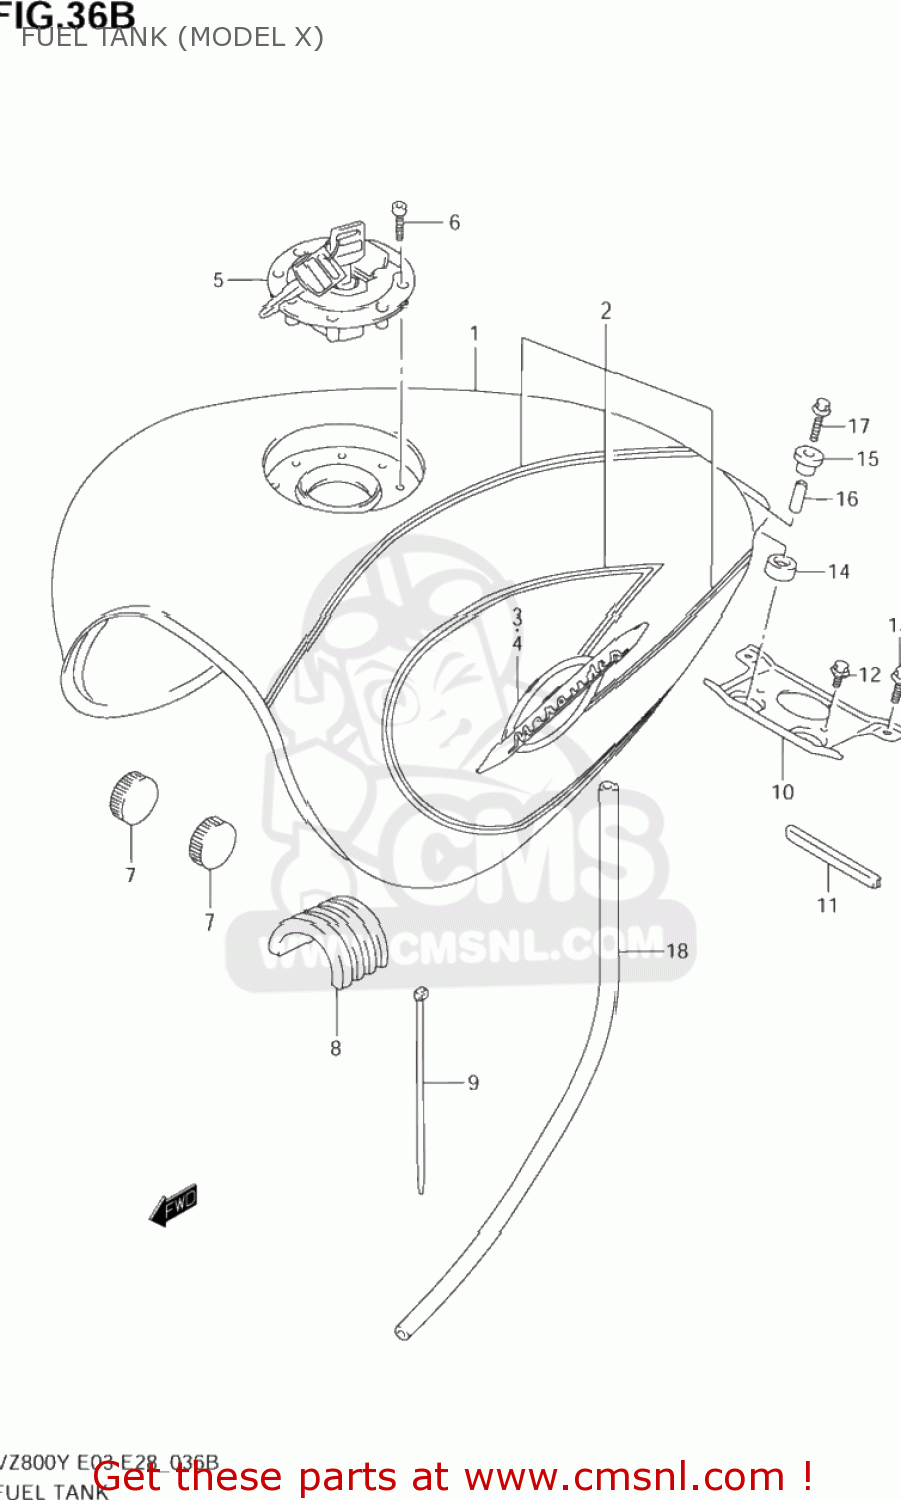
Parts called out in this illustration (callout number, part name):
1	TANK ASSEMBLY,FUEL
2	TAPE SET,FUEL TANK
3	EMBLEM,FUEL TANK,R
4	EMBLEM,FUEL TANK,L
5	CAP SET,FUEL TANK
6	BOLT(5X20)
7	CUSHION
8	CUSHION,FUEL TANK UPR
9	CLAMP(L:250)
10	BRACKET,FUEL TANK RR
11	PROTECTOR
12	BOLT
13	BOLT
14	CUSHION,FUEL TANK RR NO.2
15	CUSHION
16	SPACER(6.5X10.5X22.5)
17	BOLT
18	HOSE,DRAIN
